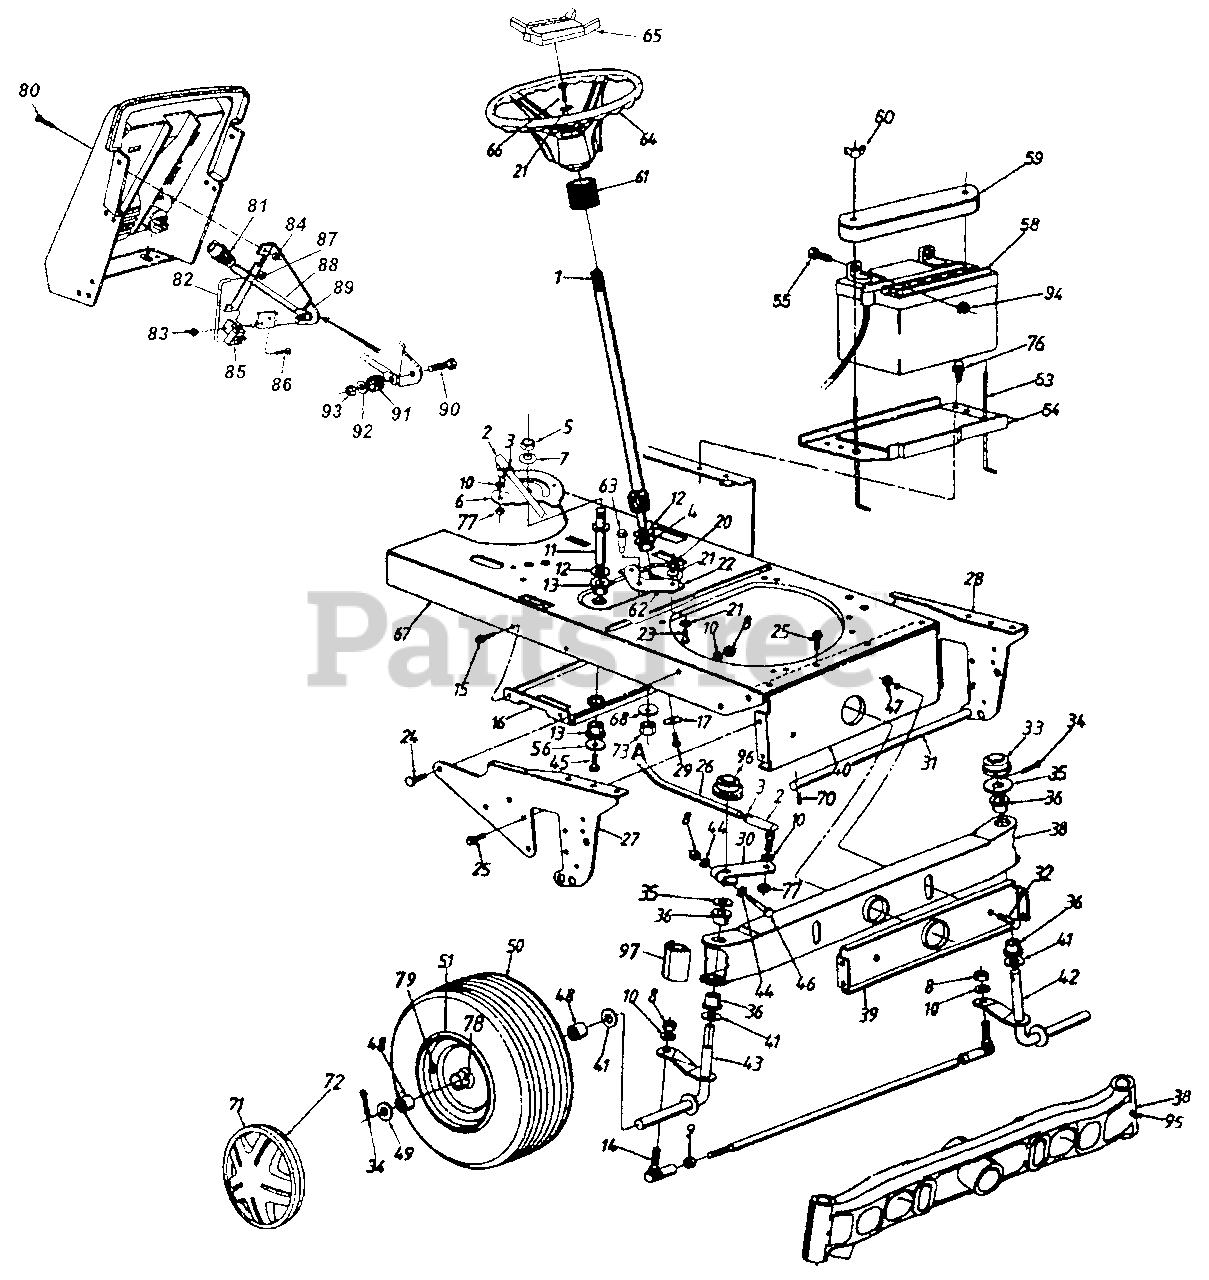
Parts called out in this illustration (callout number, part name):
1	Steering Shaft Ass'y.
2	Ball Joint 7/16-20 Thd.
3	Hex Jam Nut 7/16-20 Thd.
4	Hex Flange Brg.
5	Hex Jam Nut 5/8-18 Thd.
6	Steering Gear Segment
7	Bell-Wash. 5/8" I.D. x 1.25" O.D.
8	Hex Nut 3/8-24 Thd.
9	Hex Jam Nut 3/8-24 Thd.
10	L-Wash. 3/8" I.D.
11	Steering Gear Segment Shaft
12	Fl-Wash. .64" I.D. x 1.24" O.D.
13	Hex Flange Brg. .63" I.D.
14	Ball Joint Ass'y.
15	Hex Wash. Hd. TT-Tap Scr.1
17	Cap
20	Hex Nut 5/16-24 Thd.
21	Bell-Wash. .345" I.D. x .88" O.D.
24	Ribbed Neck Bolt 3/8-24 x .8" Lg.
25	Hex Wash. TT-Tap Scr.
26	Steering Drag Link
31	Deck Connecting Rod
32	Shld. Bolt .498" Dia. x 2.45" Lg.
33	Cap
34	Cotter Pin 5/32" Dia.
35	Flat Washer
36	Flange Brg. .757" I.D
41	Fl-Wash. .76" I.D. x 1.49" O.D.
42	Front Axle Ass'y. - L.H.
43	Front Axle Ass'y. - R.H.
44	Bowed Washer
45	Hex L-Scr. 5/16-18 x .62" Lg.
46	Hex Bolt 3/8-24 x 2.25" Lg.
47	Hex L-Nut 3/8-16 Thd.
48	Flange Brg. .75" I.D.
49	Fl-Wash. .71" I.D. x 1.5" O.D.
56	Fl-Wash. .33" I.D. x 1.25" O.D.
58	Battery
59	Battery Cover
60	Wing Nut Plastic 1/4-20 Thd.
61	Steering Bellow
64	Steering Wheel
65	Steering Insert
66	Hex L-Bolt 5/16-18 x 1" Lg.
70	Internal Cotter Pin
71	Hub Cap
72	Spring Clip
73	Hex Nut 3/8-16 Thd.
76	Hex Wash. B-Tap Scr. 1/4 x .62" Lg.
77	Hex Jam L-Nut 3/8-24 Thd.
78	Grease Fitting
79	Air Valve
80	Truss Scr. 1/4-20 x .5" Lg.
81	Knob
82	Deck Control Rod
83	Hex Sems Nut #10-24 Thd.
84	Hex Sems Nut 1/4-20 Thd.
85	Safety Switch
86	Truss Mach. Scr. #10-24 x .5" Lg.
87	Push Nut
88	Blade Clutch Lever
91	Rubber Washer
92	Fl-Wash. .281" I.D. x .73"
93	Hex L-Nut 1/4-20 Thd.
94	Hex L-Nut 1/4-20 Thd.
95	Grease Fitting
97	End Cap
